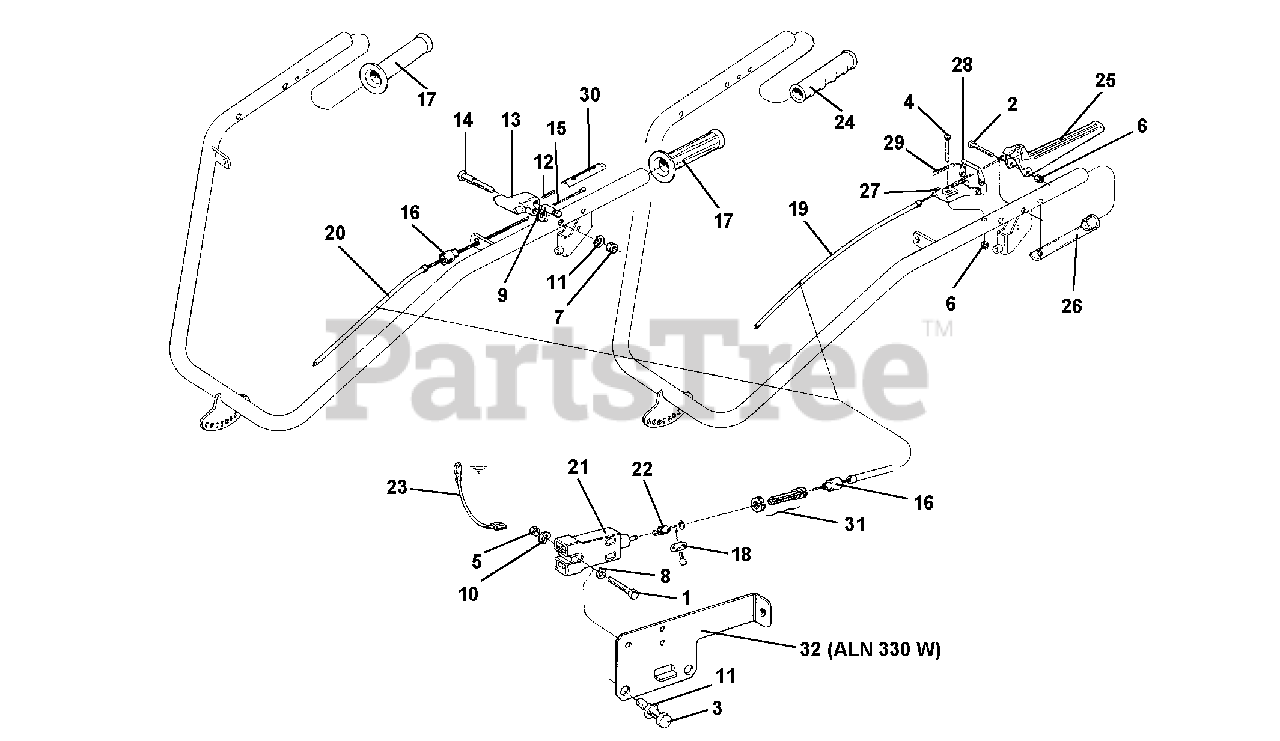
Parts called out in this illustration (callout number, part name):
1	SCREW TE M4 X 25
2	SCREW TE M6 X 45
3	SCREW TE M8 X 12
4	SCREW TSV M6 X 40
6	NUT, SELF LOCKING M6
7	NUT, SELF LOCKING M8
8	FLAT WASHER 4.3
9	WASHER, FLAT 8.4
10	LOCK WASHER B 4.3
11	WASHER, LOCK 8.4
12	PIN, LOCKING 4 X 20
13	LOCKING LEVER
15	DRILLED PIN
16	END, SHEATH
17	KNOB RUBBER HOLE D 25
18	CABLE CLAMP
19	SHEATH CABLE
20	SHEATH CABLE
21	STOP SWITCH
22	SWITCH SPRING
23	SWITCH CABLES
25	MOVABLE MOTOR STOP BODY
27	SHEATH LOCK
28	MOVABLE BODY LOCK
30	RUN-STOP LABEL
31	ADJUSTING SCREW
32	SUPPORT OR ACME STOP SWITCH
